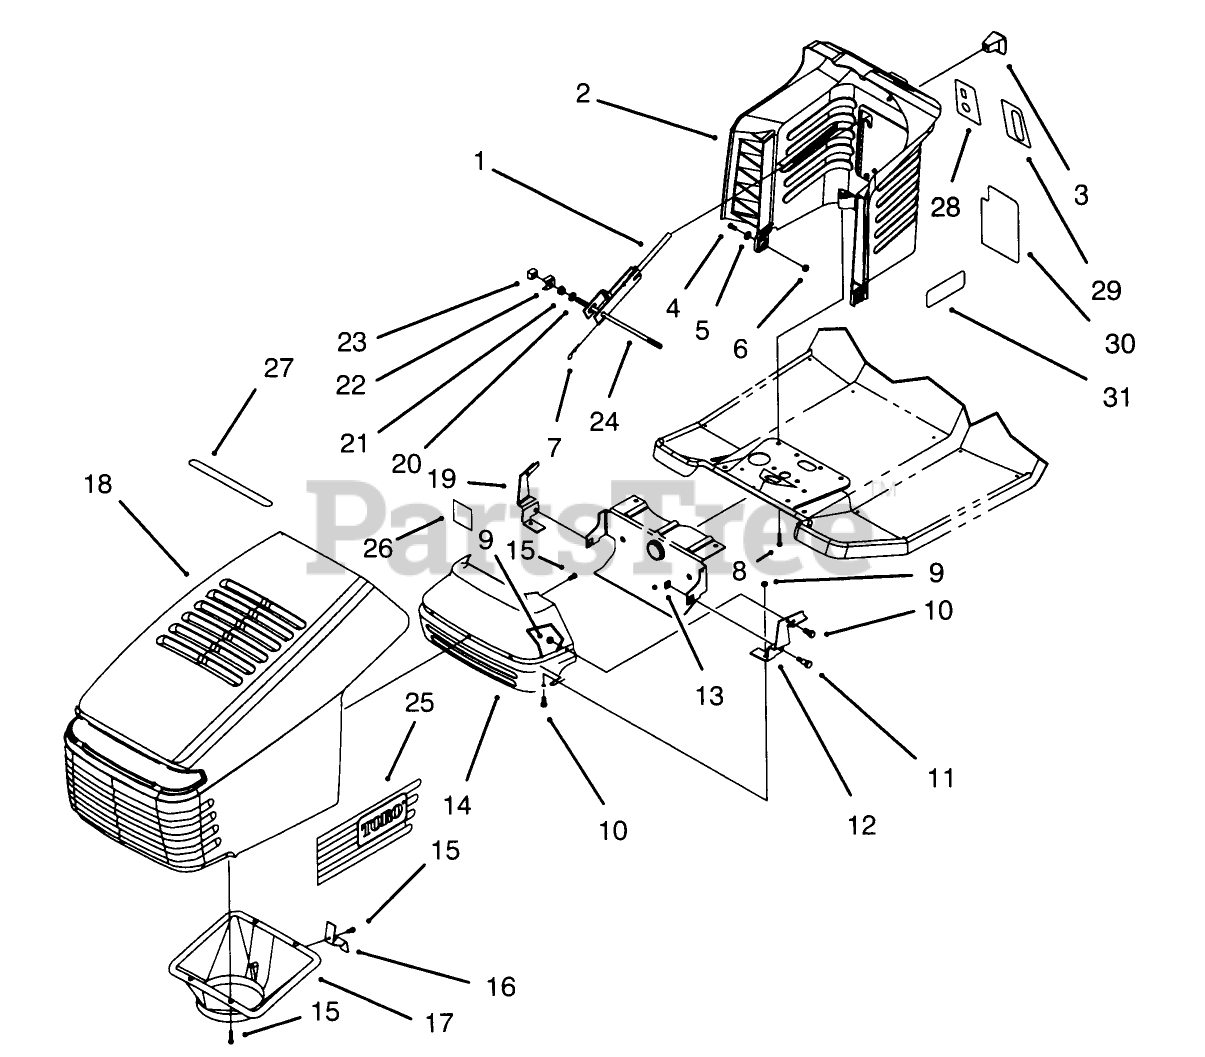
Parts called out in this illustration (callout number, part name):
3	SHIFT KNOB
4	SCREW-HH
5	WASHER-PLAIN
6	NUT-LOCK, NI
8	SCREW-HWH
9	NUT-LOCK, NI
10	SCREW-HH
11	BOLT-SHOULDER
13	NUT-RETAINER
15	SCREW-PLASTITE
16	HOOD LATCH
17	DUCT-AIR
18	HOOD ASM
20	WASHER-FLAT
21	NUT-FLANGE
22	ROD-CLAMP PIVOT
24	ROD-TOWER PIVOT
25	DECAL - HOOD LEFT
26	PICK AS EACH
27	DECAL-AIR DUCT
28	DECAL - IGNITION
29	DECAL-THROTTLE/CHOKE
30	DECAL-DECK, ENGAGE
31	DECAL-1232XL
